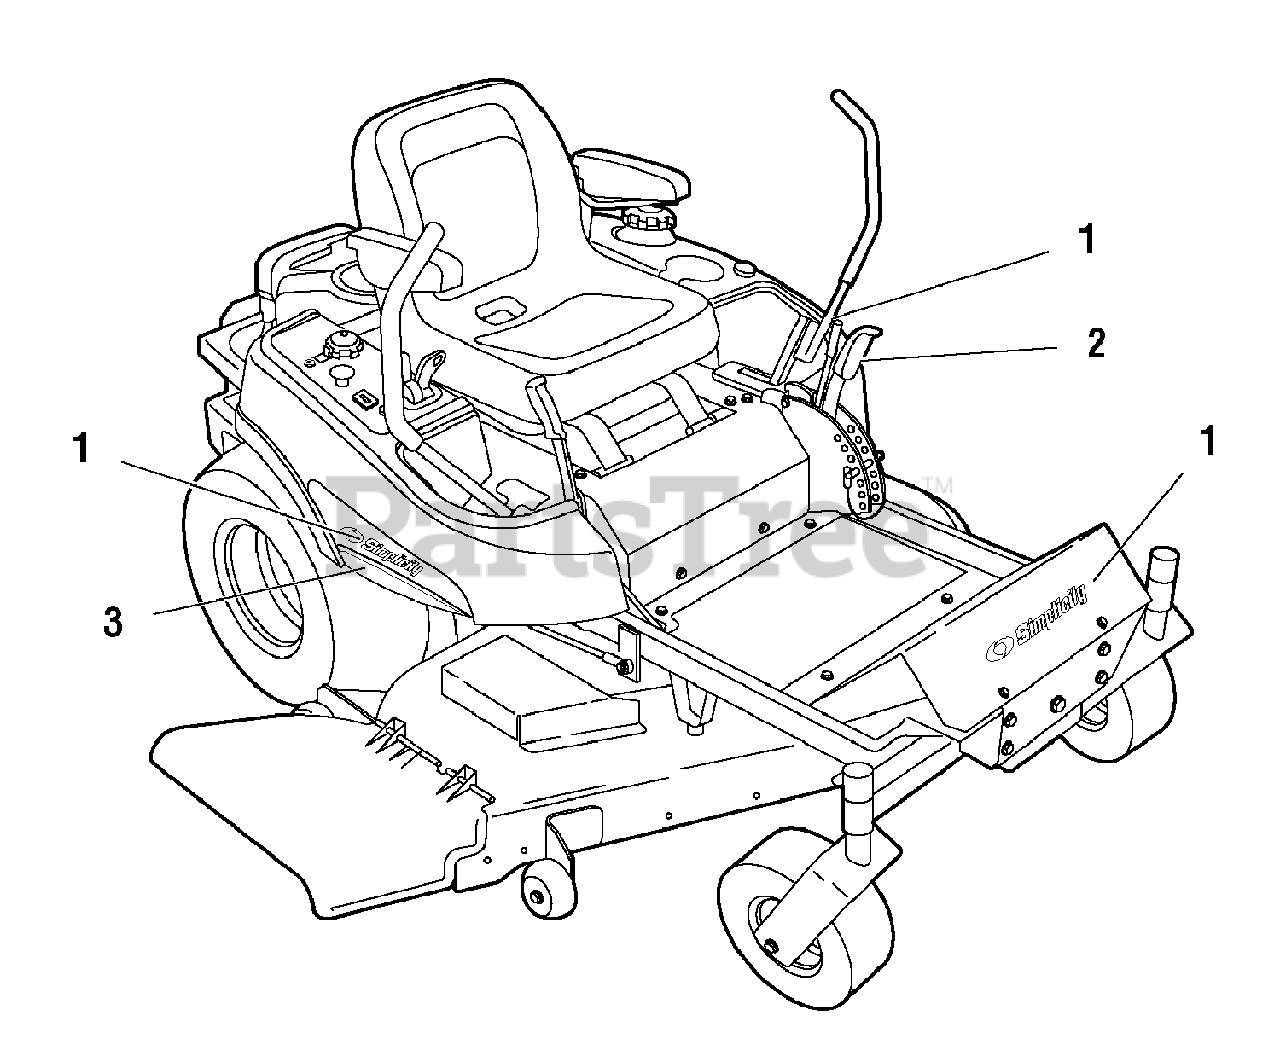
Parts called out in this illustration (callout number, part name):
1	DECAL, Simplicity, Silver & Blue, w/Icon
1	DECAL, Massey Stripe
2	DECAL, Stripe, LH, Simplicity
2	DECAL, Tank Badge, LH, Massey Ferguson
3	DECAL, Stripe, RH, Simplicity
3	DECAL, Tank Badge, RH, Massey Ferguson
4	DECAL, Massey, ZT1844
